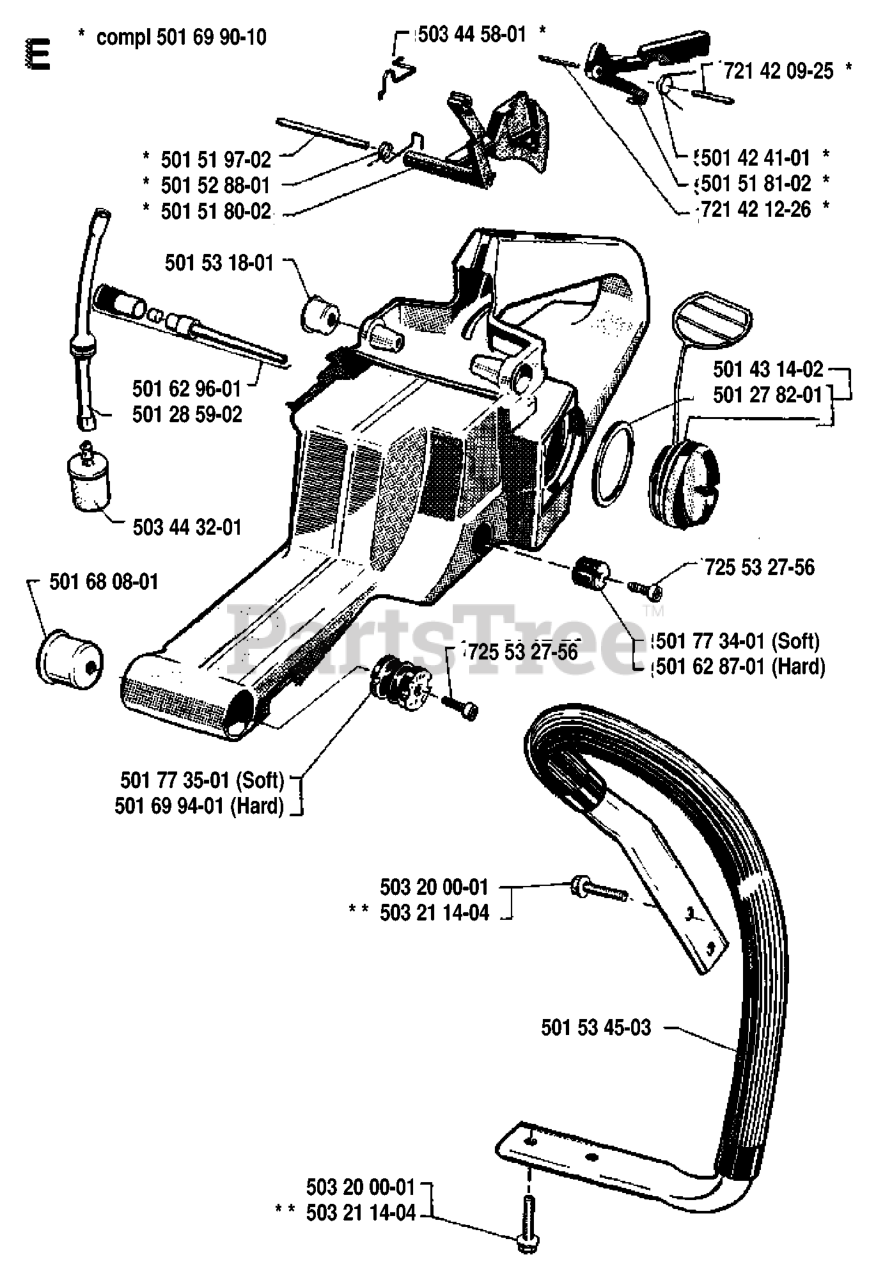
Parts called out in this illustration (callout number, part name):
2	LABEL
3	DECAL
4	DECAL 80 DBA
5	DECAL, ENG. HP
6	DECAL
7	RP.DECAL.BADGE.170MM.TEXTLOGO
8	DECAL
10	DECAL BTRY SYMBOLS
11	DECAL.INTERNATIONL.CUTFINGER
16	DECAL
17	DECAL PARK BRAKE
